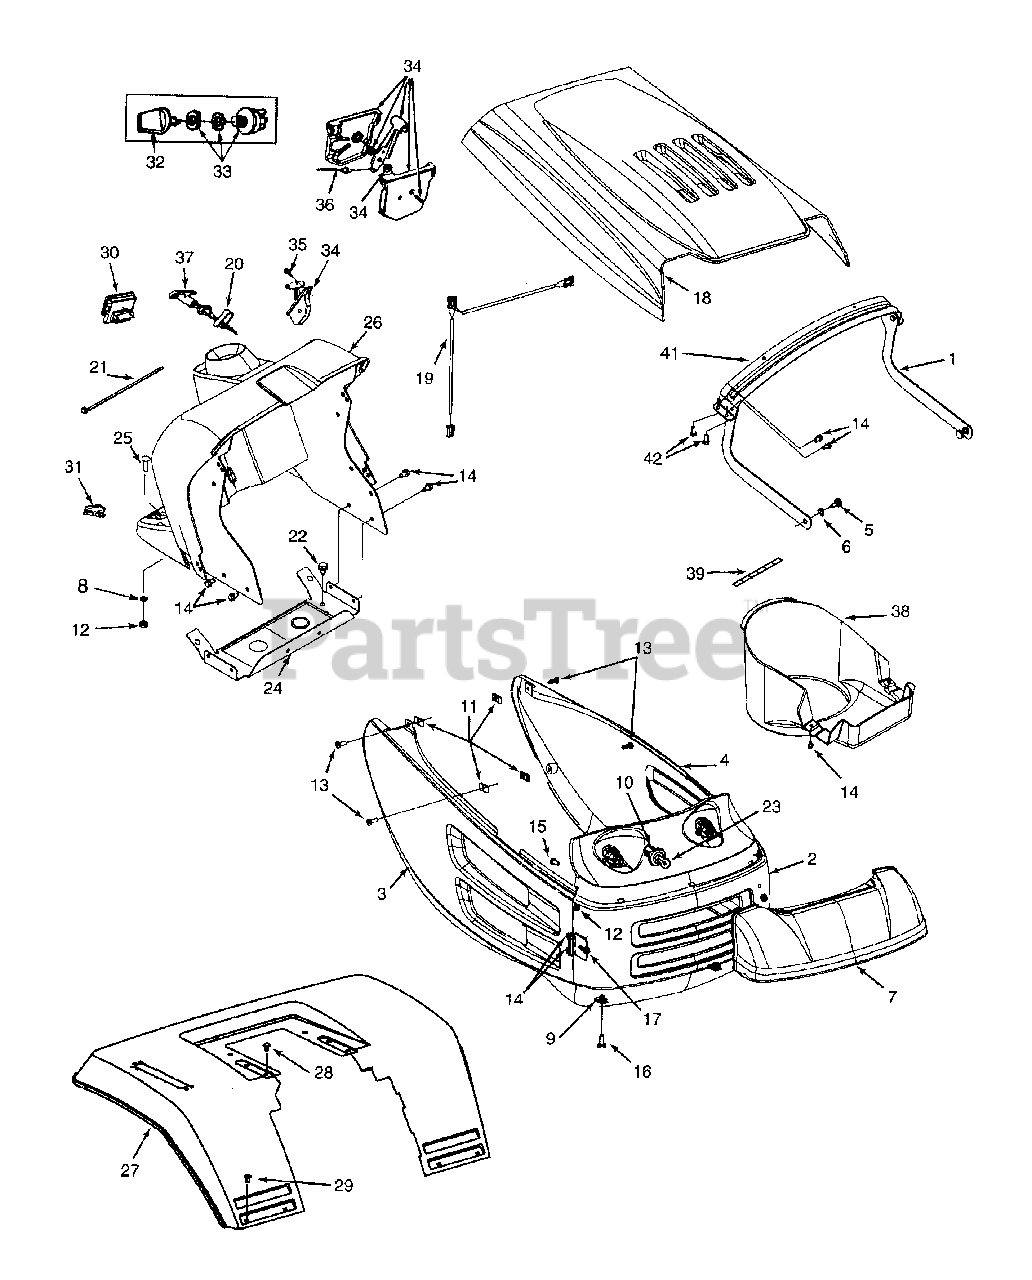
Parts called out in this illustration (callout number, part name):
6	Spr. Wash. .39" I.D. x .62" O.D.
7	Lens
8	Retainer Nut
9	U - Nut 5/16-18 Thd
10	Socket
11	Tinn. Nut 1/4-20 Thd.
12	Hex Sems Nut 1/4-20 Thd.
13	Pan Hd. Mach. Scr. 1/4-20 x .75" Lg.
14	Hex Wash. Hd. TT-Tap Scr. 1/4-20 x .5" Lg.
15	Hex Bolt 1/4-20 x .625" Lg.
16	Hex Bolt 5/16-18 x .75" Lg.
19	Headlight Harness
20	Choke Retainer
21	Cable Tie
22	Hex Wash. Hd. Tap Scr. 5/16-18 x .5" Lg.
23	Lamp
26	Dash Panel
29	Truss Mach. Scr. 1/4-20 x .5" Lg.
30	Ammeter
31	Light Switch
32	Ignition Key
33	Ignition Switch
34	Throttle Box Ass'y.
35	Truss Mach. AB-Tap Scr. #10 x .5"
36	Throttle Control Wire 18.5" Lg.
37	Choke Control 20" Lg.
37	Choke Control 23" Lg.
38	Heat Duct
39	2-Sided Tape
